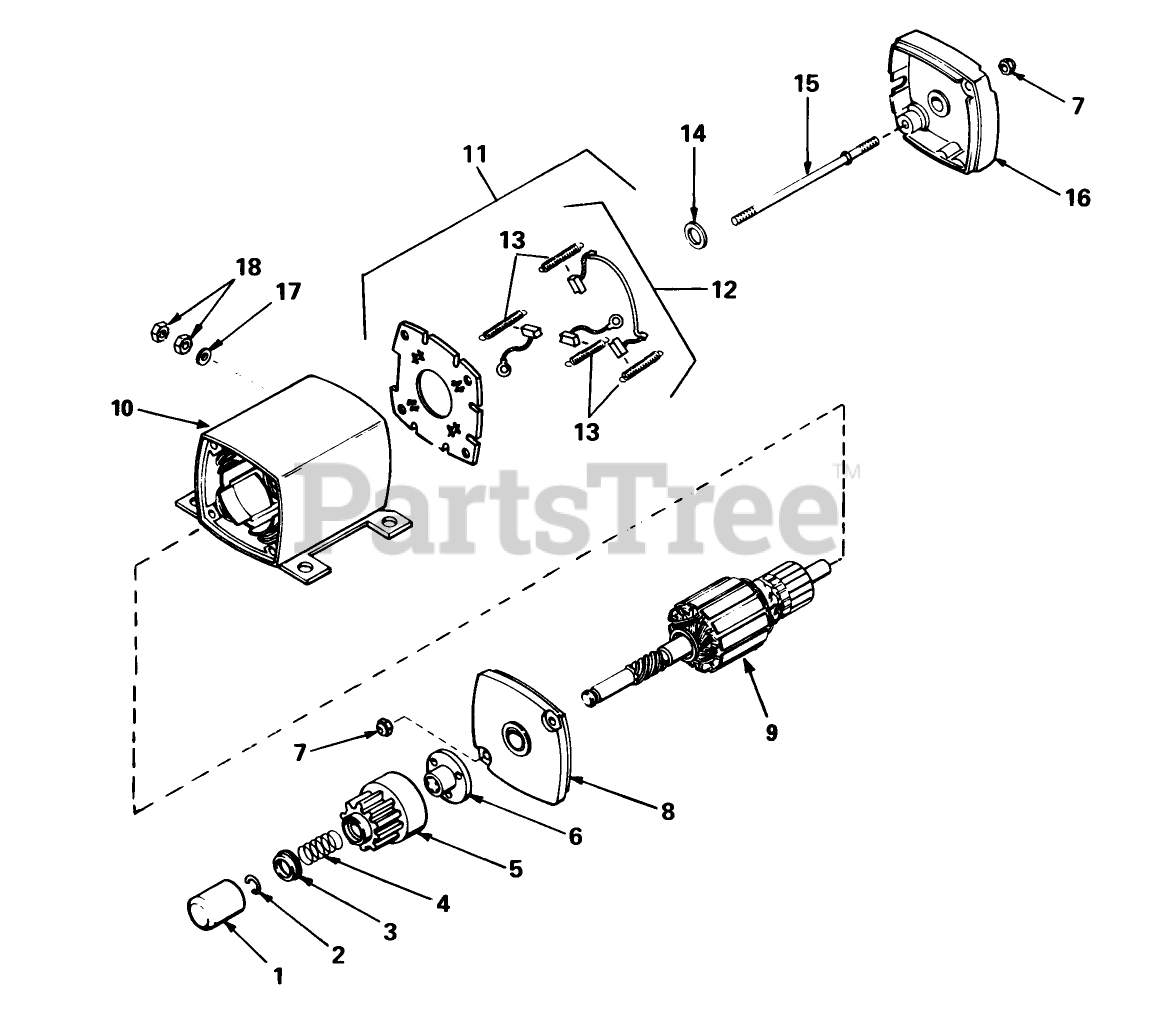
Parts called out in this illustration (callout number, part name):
1	Cover-Dust
2	Ring-Retainer
3	Retainer-Spring
4	Spring-Anti Drift
5	Gear
6	Nut-Engaging
7	Nut-Lock
8	Cap Assy., Drive End
9	Armature
10	Housing Assembly (Incl. Ref. #11)
11	Card Assy., Brush (Incl. No. 12)
12	Brush Spring Kit (Incl. 4 pcs. of #13)
13	1545D SUP TO W/3256
14	Washer-Thrust
15	Bolt
16	2035A67 WIZARD W/34
17	Washer
18	Nut-Hex
